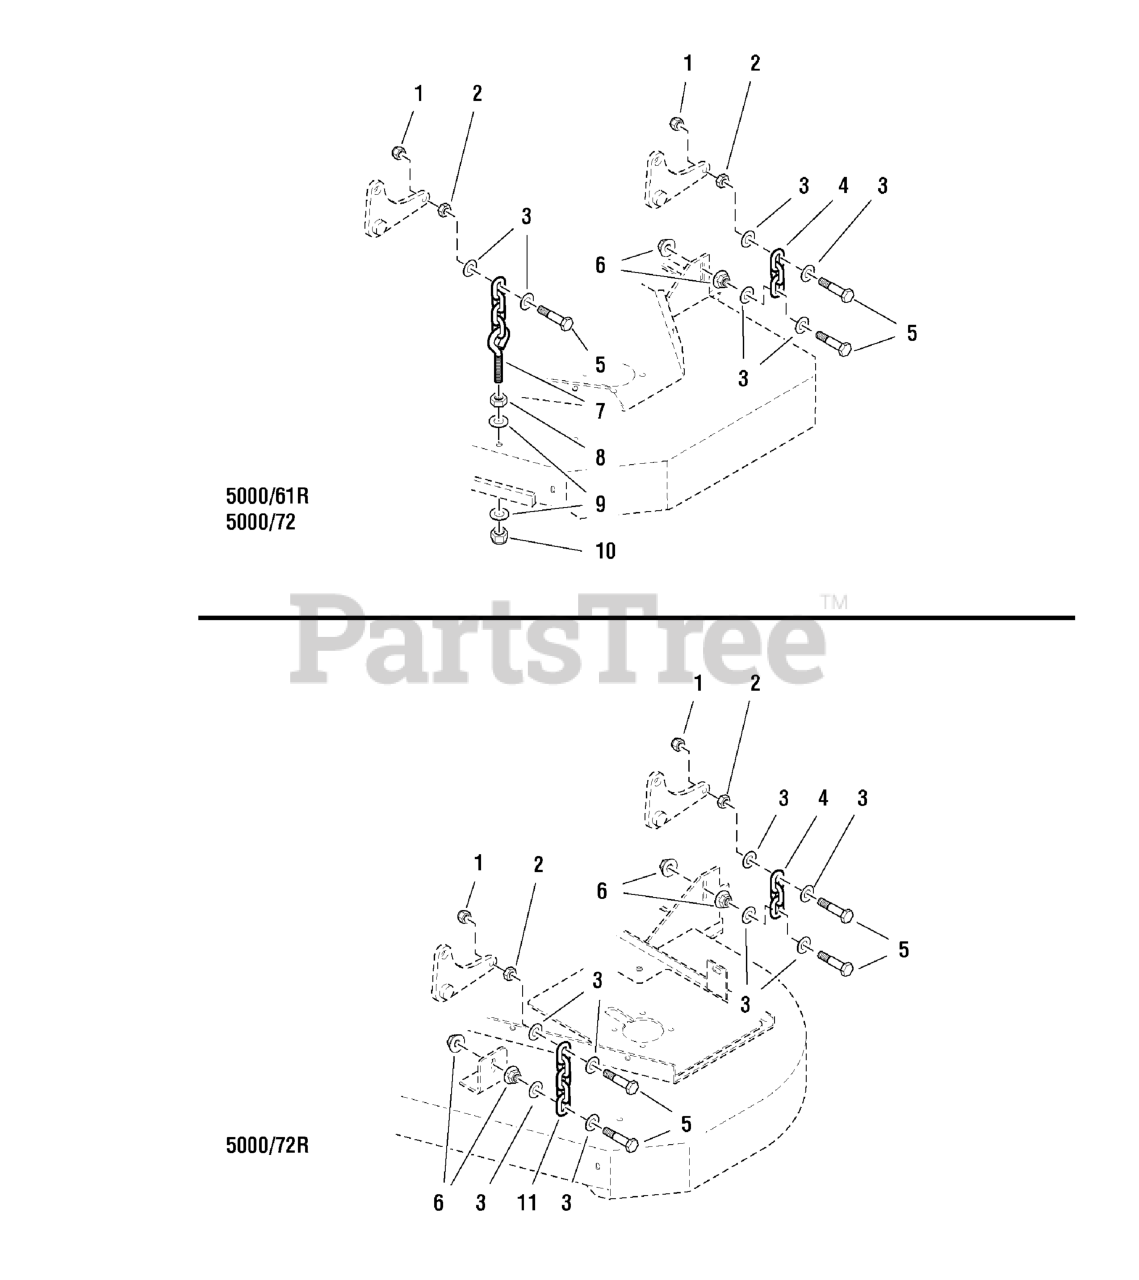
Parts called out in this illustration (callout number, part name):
1	NUT, 3/8-16 HEX NYLON LOCK
2	NUT, 3/8-16 HEX JAM
3	WASHER, 3/8 SAE
4	CHAIN, 3 LINKS
5	BOLT, 3/8-16 X 1-3/4" GD5 CZ
6	NUT, 3/8-16 Hex Serrated Flange
7	HANGER, FRONT DECK - 4 LINK, 5.5" EB
8	NUT, 1/2-13 Hex
9	WASHER, 1/2 SAE
10	NUT, 1/2-13 HEX NYLON LOCK
11	CHAIN, 5 LINKS
